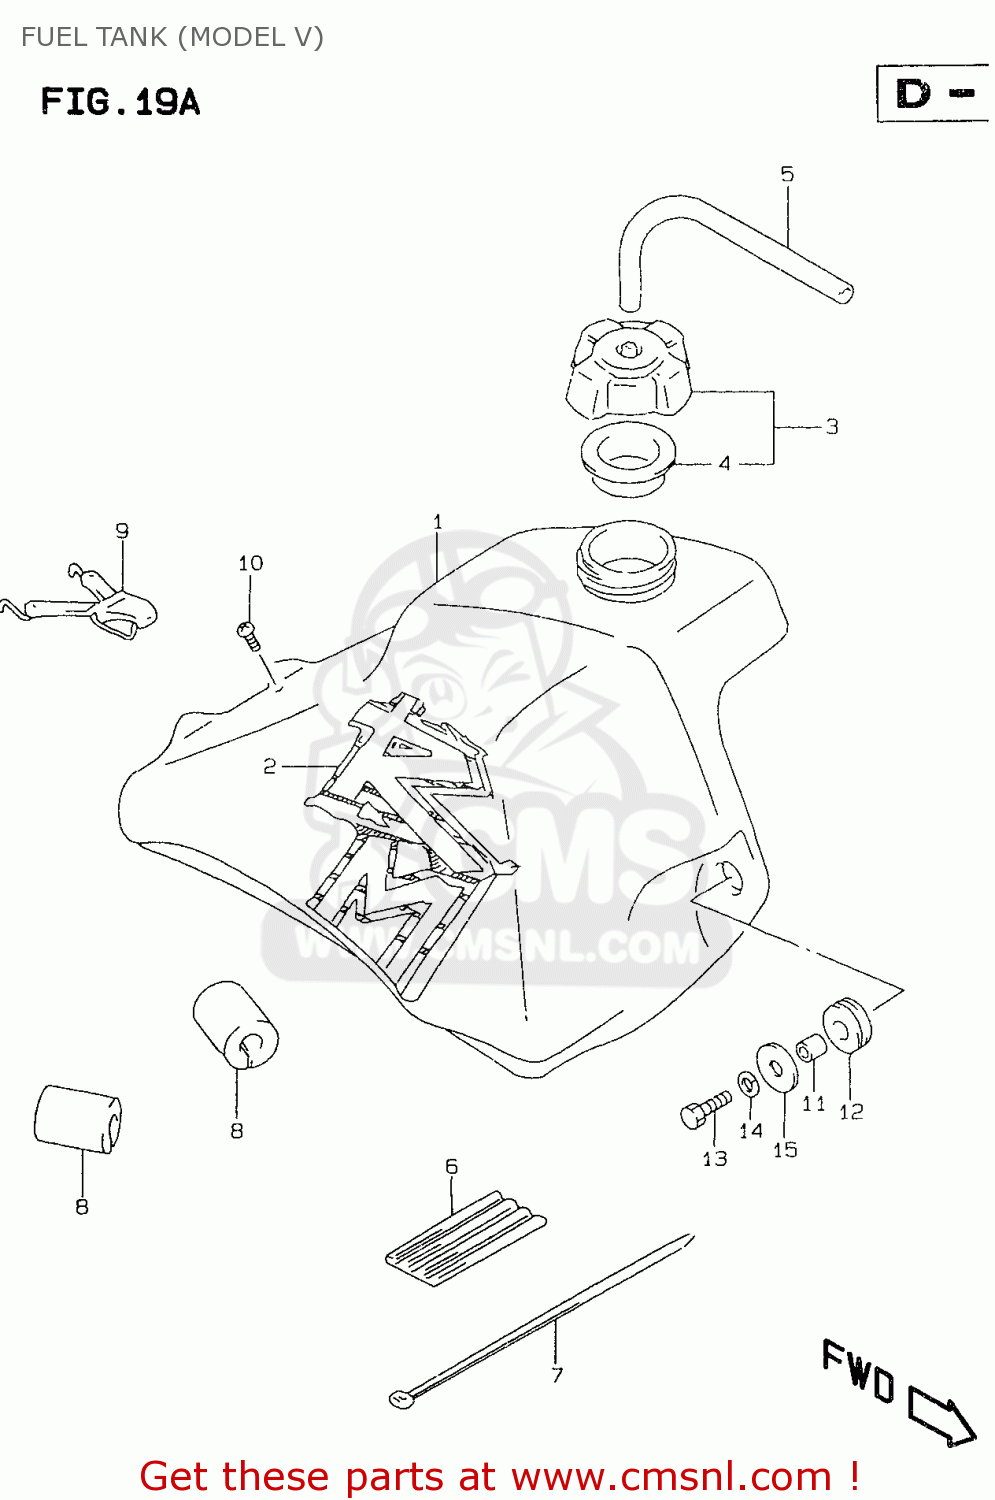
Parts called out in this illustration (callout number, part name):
1	TANK,FUEL(YELLOW)
2	EMBLEM,FUEL TANK
3	CAP SET,FUEL TANK
4	GASKET,CAP (NAS)
5	HOSE(5X8.2X600)
6	CUSHION,FUEL TANK UPR FR
7	CLAMP(L:250)
8	CUSHION,FUEL TANK UPR RR
9	BAND,FUEL TANK RR
10	SCREW
11	SPACER(6.5X10X11.5)
12	CUSHION
13	BOLT
14	LOCK WASHER
15	WASHER (6.5X24X1.6)
